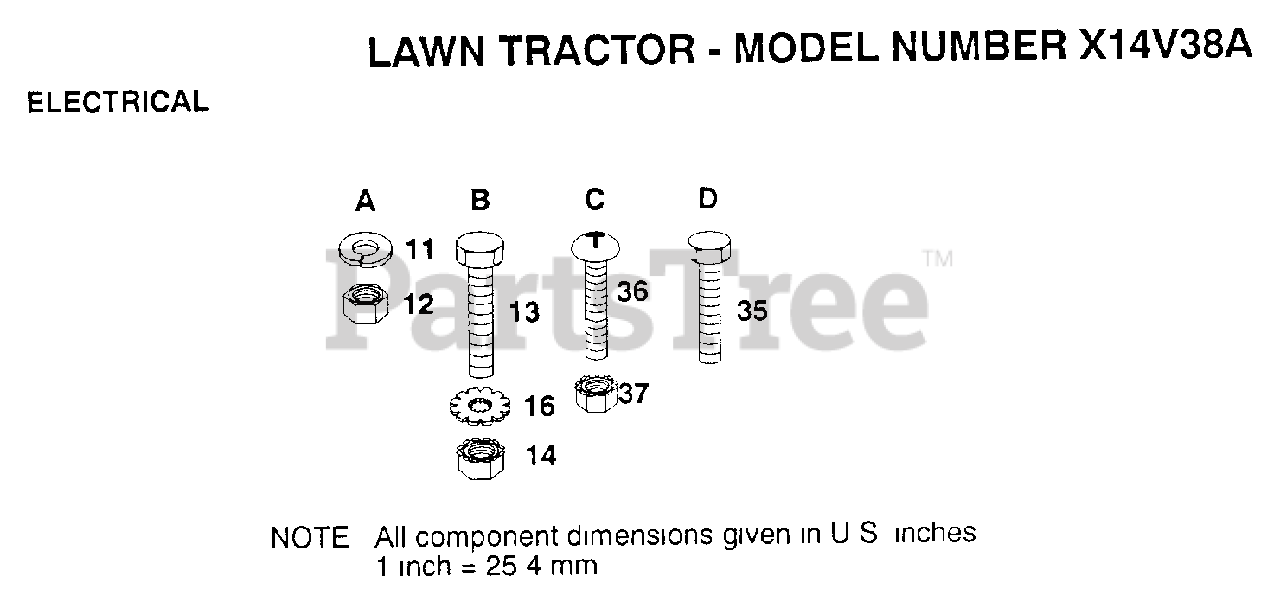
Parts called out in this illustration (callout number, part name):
12	NUT
13	BOLT
14	NUT
35	SCREW
37	"NUT,KEPS"
